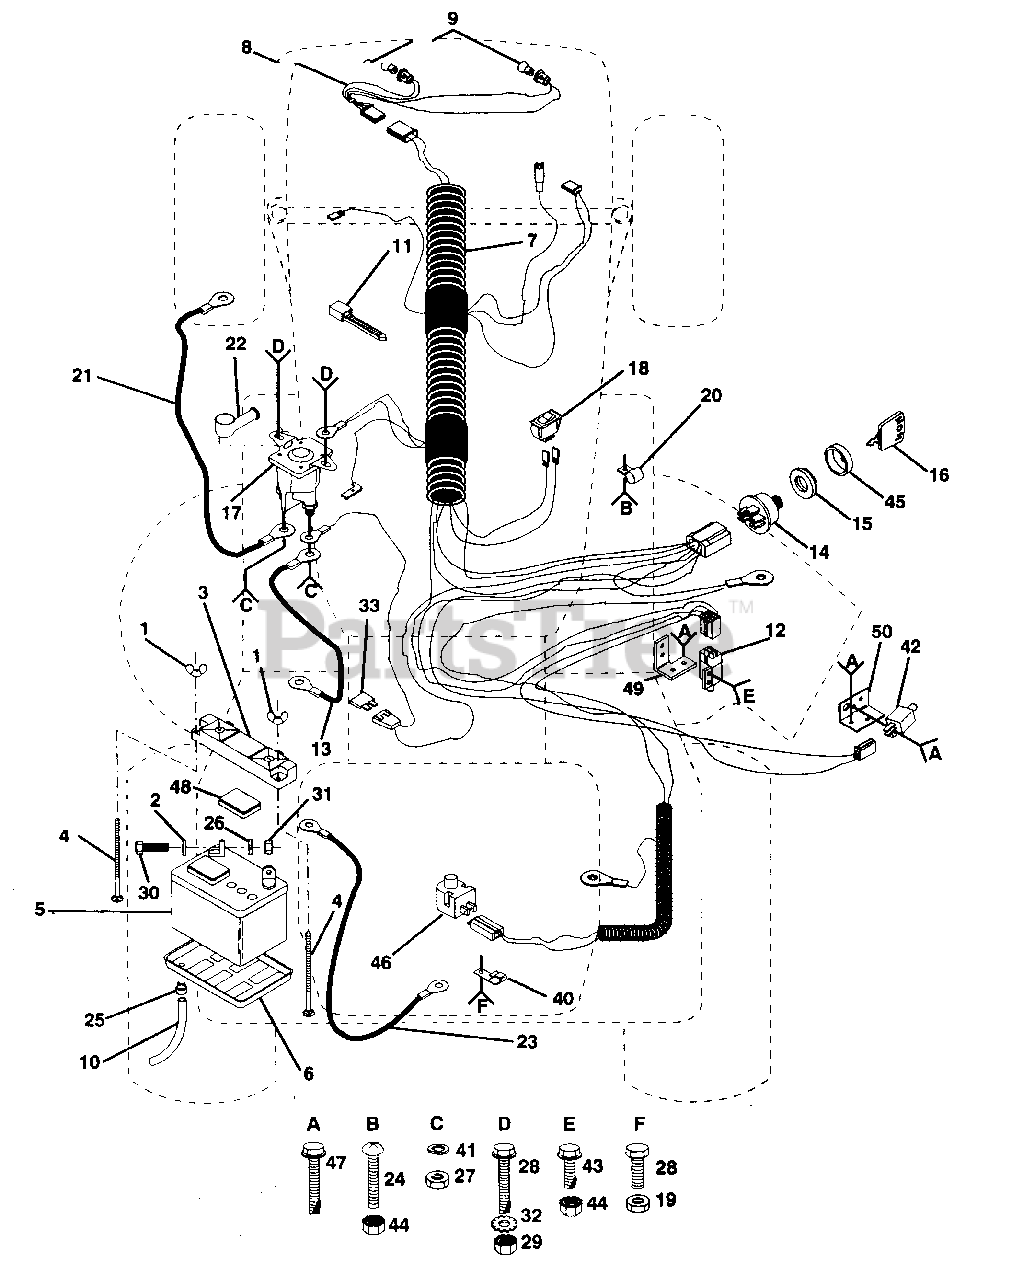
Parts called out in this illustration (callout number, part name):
1	Nut, Wing 1/4-20 (AYP part number)
2	Washer 9/32 x 5/8 x 16 Gauge (AYP part number)
3	Guard, Terminal (AYP part number)
4	Bolt, Carriage 1/4-20 x 7-1/2 (AYP part number)
5	Battery (AYP part number)
6	Tray, Battery (AYP part number)
7	Harness, Ignition
8	Harness, Socket, Light (AYP part number)
9	Bulb, Light (AYP part number)
10	Tube, Tray, Battery (AYP part number)
11	Tie, Cable (AYP part number)
12	Switch, Clutch, Attachment, Interlock (AYP part number)
13	Cable, Battery (AYP part number)
14	Switch, Ignition (AYP part number)
15	Nut, Ignition (AYP part number)
16	Key (AYP part number)
17	Solenoid (AYP part number)
18	Switch, Light (AYP part number)
19	Nut, Hex 1/4-20 (AYP part number)
20	Clip, Wire (AYP part number)
21	Cable, Battery (AYP part number)
22	Cover, Terminal (AYP part number)
23	Cable, Battery (AYP part number)
24	Screw #10/32 x 1/2 Pan Head UNF (AYP part number)
25	Clamp, Hose (AYP part number)
26	Washer, Lock Heavy Helical 1/4 (AYP part number)
27	Nut, Hex Jam 1/4-20 (AYP part number)
28	Bolt, Hex 1/4-20 x 1/2 Grade 5 (AYP part number)
29	Nut, Keps, Hex 1/4-20 (AYP part number)
30	Bolt, Hex 1/4-20 x 3/4 (AYP part number)
31	Nut, Hex 1/4-20 (AYP part number)
32	Washer, Lock External Tooth 1/4 (AYP part number)
33	Fuse (AYP part number)
40	Clip, Insulated (AYP part number)
41	Washer, Lock 1/4 (AYP part number)
42	Switch, Interlock, Clutch Pedal (AYP part number)
43	Screw, Hex Washer Head (AYP part number)
44	Nut, Keps #10-32 UNF (AYP part number)
45	Bezel, Ignition (AYP part number)
46	Switch, Plunger (AYP part number)
47	Screw, Hex Tapping #10-24 x 1/2 (AYP part number)
48	Caps, Battery (Set) (AYP part number)
49	Bracket, Switch, Interlock (AYP part number)
50	Bracket, Switch (AYP part number)
